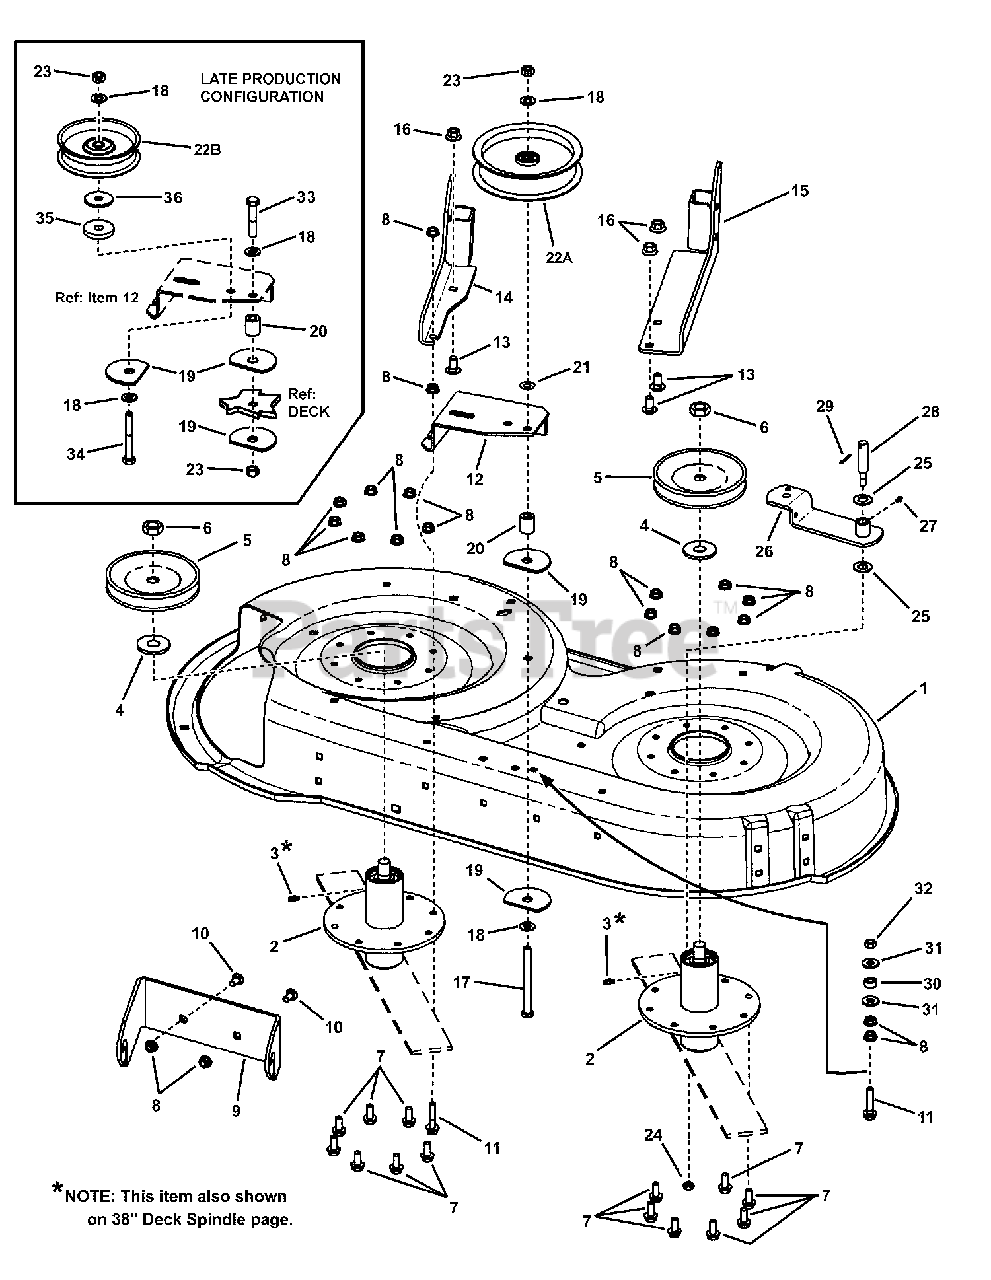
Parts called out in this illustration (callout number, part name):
1	DECK, 38 RZT (Cardinal Red)
2	ASSEMBLY, 38" Spindle
3	FITTING, Lube, Press-In (for .187 dia. Hole)
4	SPACER, 38 Spindle Pulley
5	PULLEY, 5.0 O. D.
6	NUT, 5/8-18 Hex Jam
7	BOLT, 5/16-18 x 3/4" Hex Flange Lock
8	NUT, 5/16-18 Hex Flange Lock, GR 5
9	BRACKET, Front, 38" RZT
10	BOLT, 5/16-18 x 3/4" Short Square Neck Carriage, GR 5
11	BOLT, 5/16-18 x 1-1/2" Hex Flange Lock, GR 5
12	WELDMENT, Idler Bracket
13	BOLT, 3/8-16 x 3/4" Short Square Neck Carriage, GR 5
14	WELDMENT, 38" Deck Support, RH
15	WELDMENT, 38" Deck Support, LH
16	NUT, 3/8-16 Hex Flange Lock
17	SCREW, 3/8-16 x 1" Hex Head Cap, GR 5
18	WASHER, 3/8" Flat SAE
19	WASHER, Special
20	SPACER, .380 I. D. x .895 long
21	RETAINER, 3/8" Bolt
22A	PULLEY, Flat Idler 5" x .375
22B	PULLEY, Flat Idler 4" x 1.24
23	NUT, 3/8-16 Hex Center Lock, GR 5 or B, YZ
24	NUT, 3/8-24 Hex Center lock
25	WASHER, .531 x 1.0 x .063 Flat
26	WELDMENT, Idler Arm, 38" RZT
27	LUBE FITTING, 3/16"
28	IDLER STUD (5/16-24 thread)
29	COTTER PIN, 3/32 x 3/4"
30	SPACER, .340 I.D. x .63 O.D. x .310 Thick
31	WASHER, 3/8" Flat
32	NUT, 5/16-18 Hex Center Lock, GR 5 or B, YZ
33	SCREW, 3/8-16 x 2" Hex Head Cap, GR 5
34	SCREW, 3/8-16 x 2-3/4" Hex Head Cap, GR 5
35	WASHER, 7/16" I.D. x 1-5/8" O.D. x .25 Flat
36	WASHER, 3/8" I.D. x 1-1/2" O.D. x .120 Flat
